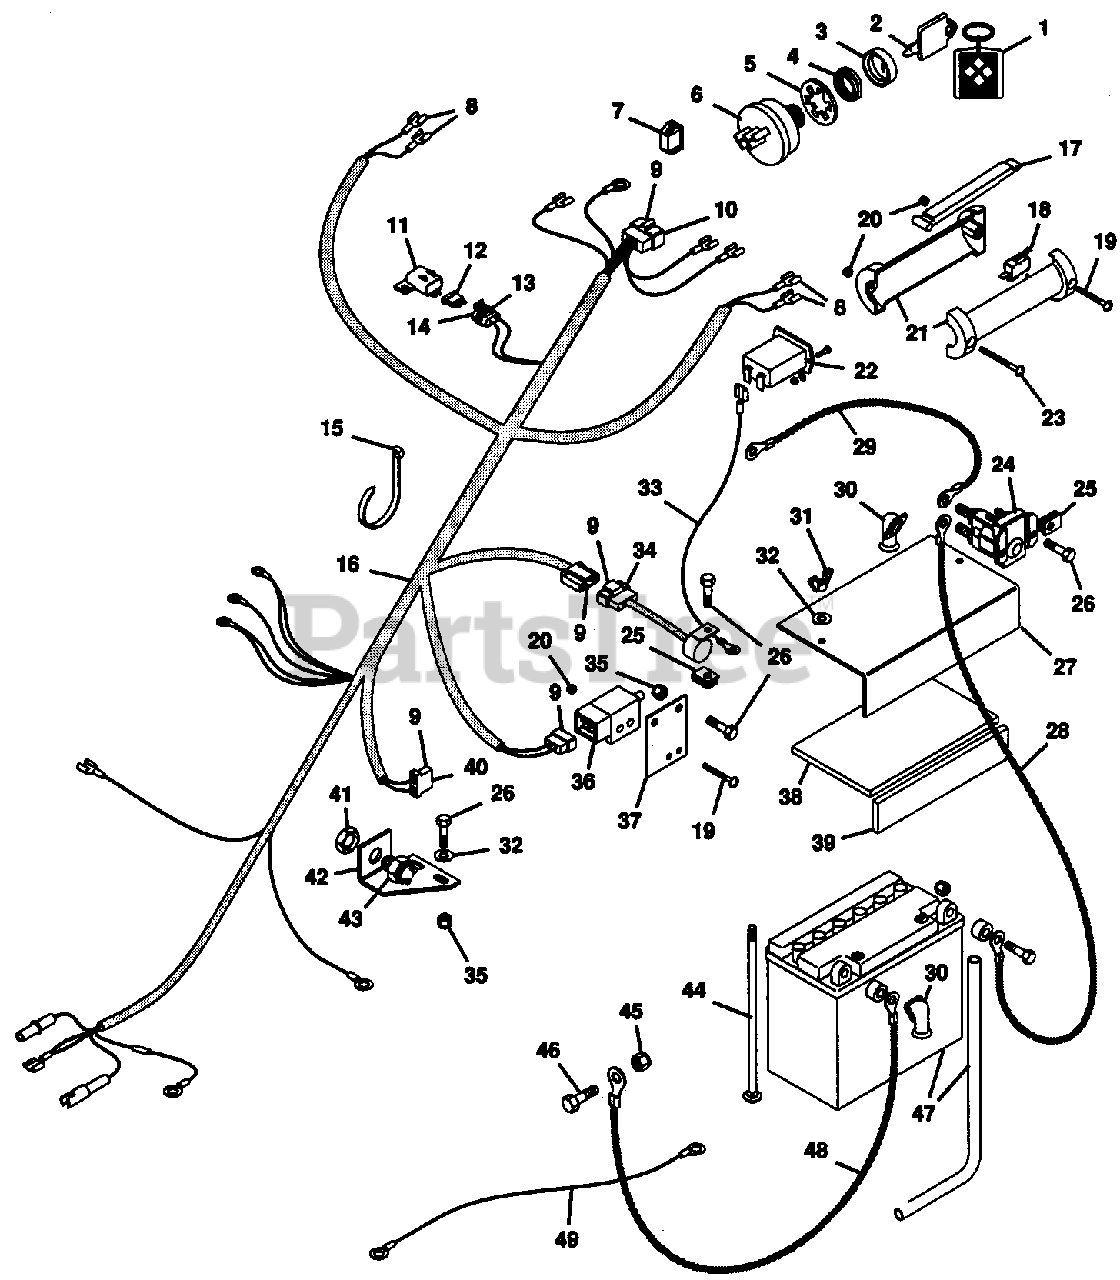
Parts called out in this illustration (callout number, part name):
1	Chain, Key
2	Key, Ignition Switch
3	Boot, for 9/16 Switch
4	Nut, 5/8-32 for Switch
5	Washer, Lock 5/8 Int. Th.
6	Switch, Ignition w/Ground
7	Light, Indicator
8	Terminal, Female
9	Terminal
10	Connector
11	Cover
12	Fuse, 25 Amp
13	Assembly, Connector
14	Terminal, for 10-12 Ga. Wire
15	Tie Wrap, Black
16	Harness, Wiring
17	Lever
18	Switch
19	Screw, Machine 10-24x.625 PHD
20	Nut, Lock 10-24
21	Handle
22	Hourmeter
23	Screw, Mach. 10-24x1.50 PHDCR
24	Switch, Magnetic
25	Nut, Speed 1/4-20
26	Bolt, Hex 1/4-20x.750
27	Cover, Battery
28	Cable, Battery to Solenoid
29	Cable, Solenoid to Starter
29	Cable, Starter
30	Boot, Battery Cable
31	Nut, Wing 1/4-20
32	Washer, Flat .281x.625x.065
33	Wire, Instrument Panel
34	Module, Interlock
35	Nut, Lock 1/4-20
36	Switch, Interlock
37	Bracket, Interlock Switch
38	Pad, Battery
39	Pad, Battery
40	Connector, 2-Wire Switch
41	Nut, Stamped 9/16-18
42	Bracket, Interlock Switch
43	Switch, Interlock
44	Bolt, 1/4-20x7.00 Rd Hd Sq Nk
45	Nut, Lock 5/16-18
46	Bolt, Hex 5/16-18x1.00
47	Battery, 12 Volt
48	Cable, Negative Battery
49	Wire, Ground
